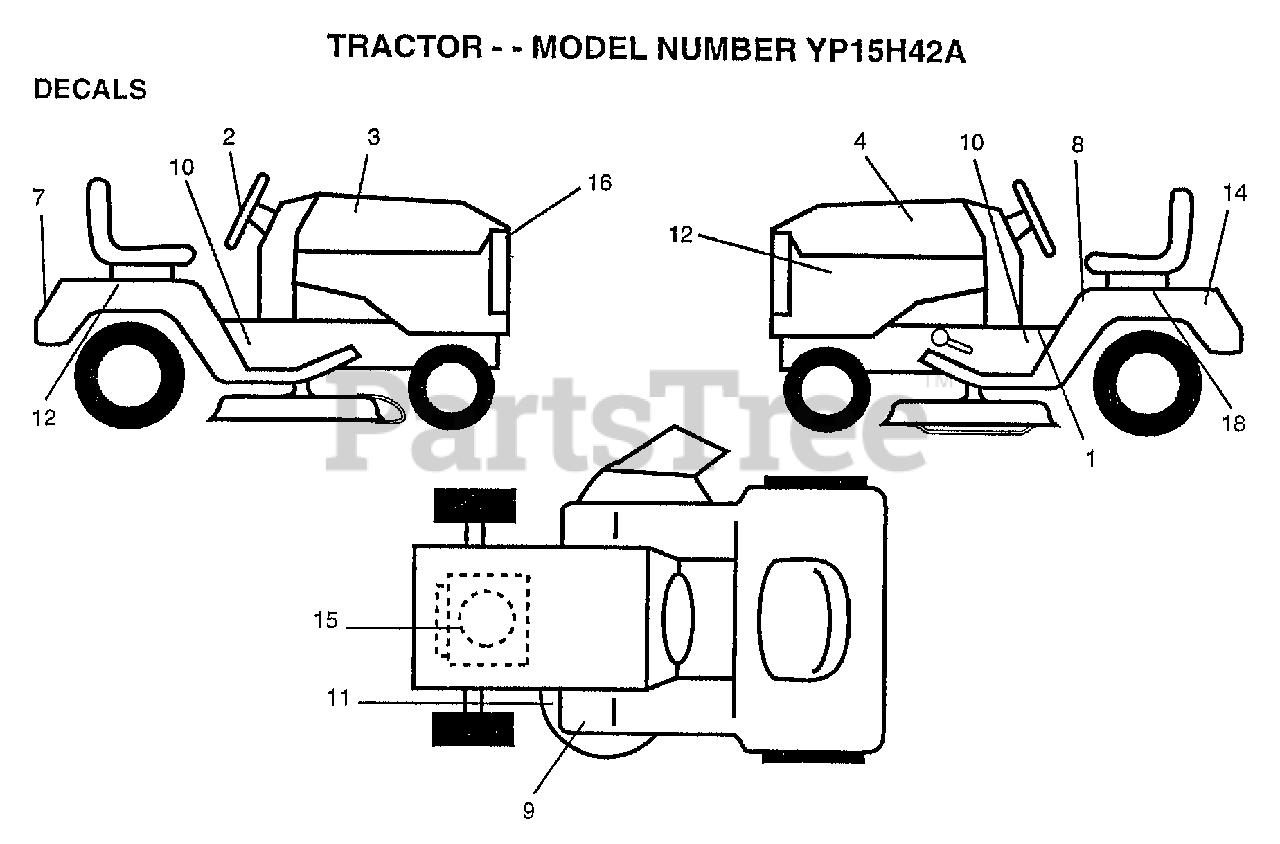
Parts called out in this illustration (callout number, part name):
1	"DECAL INST,SADDLE"
2	DECAL INS STRG WH
3	"DECAL HOOD,RH"
4	"DECAL HOOD,LH"
7	DECAL FENDER
8	"DECAL DANGER,FEND"
11	DECAL
14	DECAL.BATRY.3-3908
17	DECAL FENDER RH
18	DECAL FENDER LH
